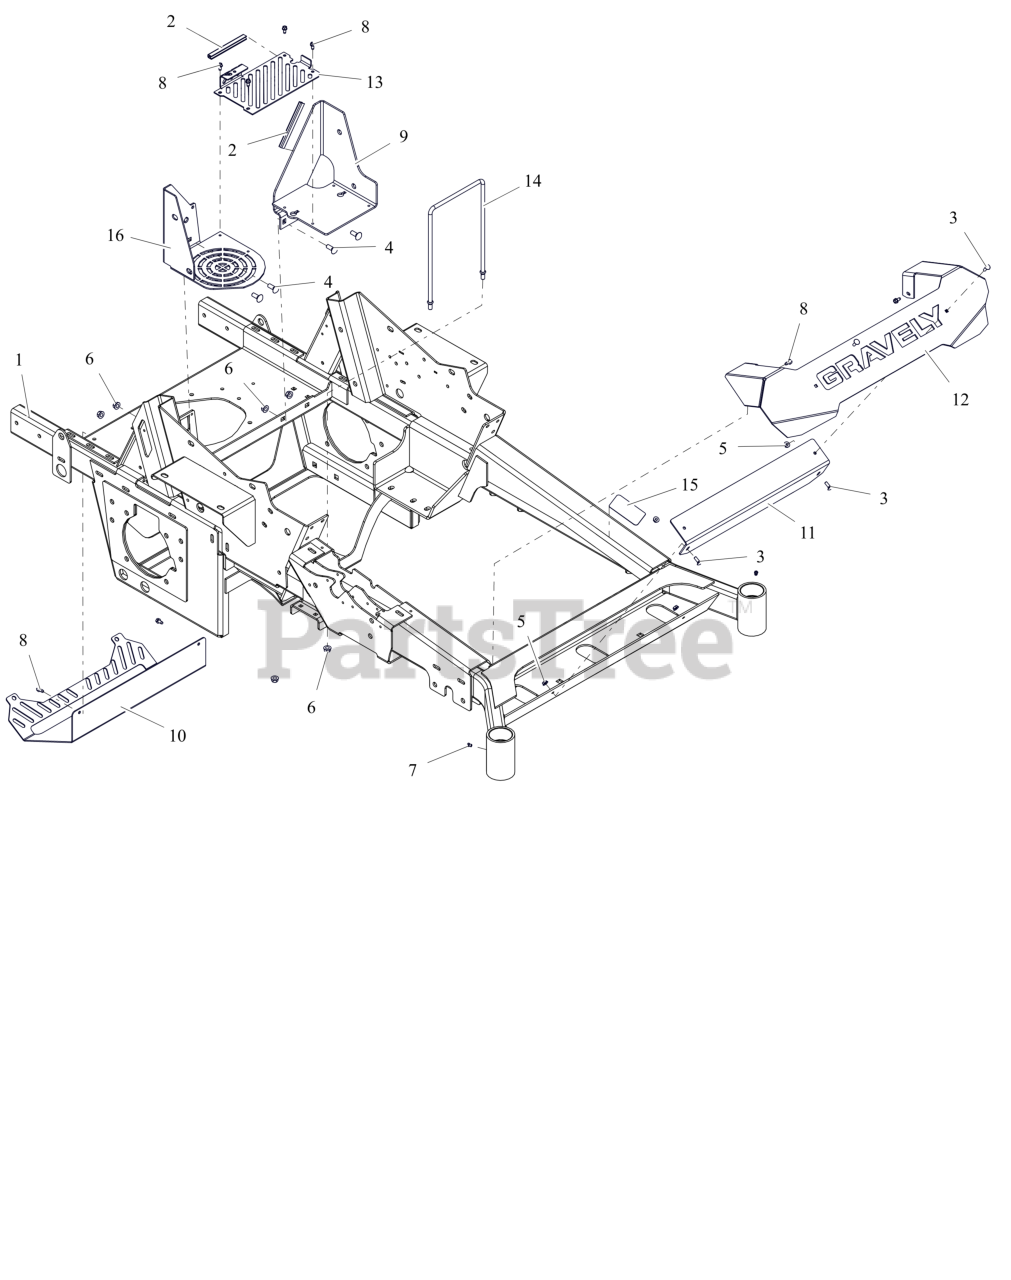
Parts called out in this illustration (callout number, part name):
1	WLDMT, 48", 52", 60" FRAME (RED)
2	STRIP, COWL
3	BLT, RHSN .25-20X.750 G5 ZCC
4	BLT, RHSN .38-16X1.00 G5 ZCC
5	NUT-LK-CTR-FLG .25-20 ZC120
6	NUT-LK-CTR-FLG .375-16 GF ZCC
7	FTG, .25-28 FLUSH MNT GREASE
8	SCR-TAP .25-20X.50 HWH ZCC
9	TRAY, BATTERY (RED)
10	GUARD, MUFFLER (BLACK)
11	BRKT, FRONT BUMPER MTG/BACKER (BLACK)
12	BMPR, 48" 52" 60" FRONT (RED)
13	GUARD, FAN CENTER (RED)
14	FINGER, PTO/TRANSAXLE BELT
15	KIT, PT300-600 ANTI-SKID Tape
16	BRKT, FAN GUARD/ROPS GUSSET (RED)
